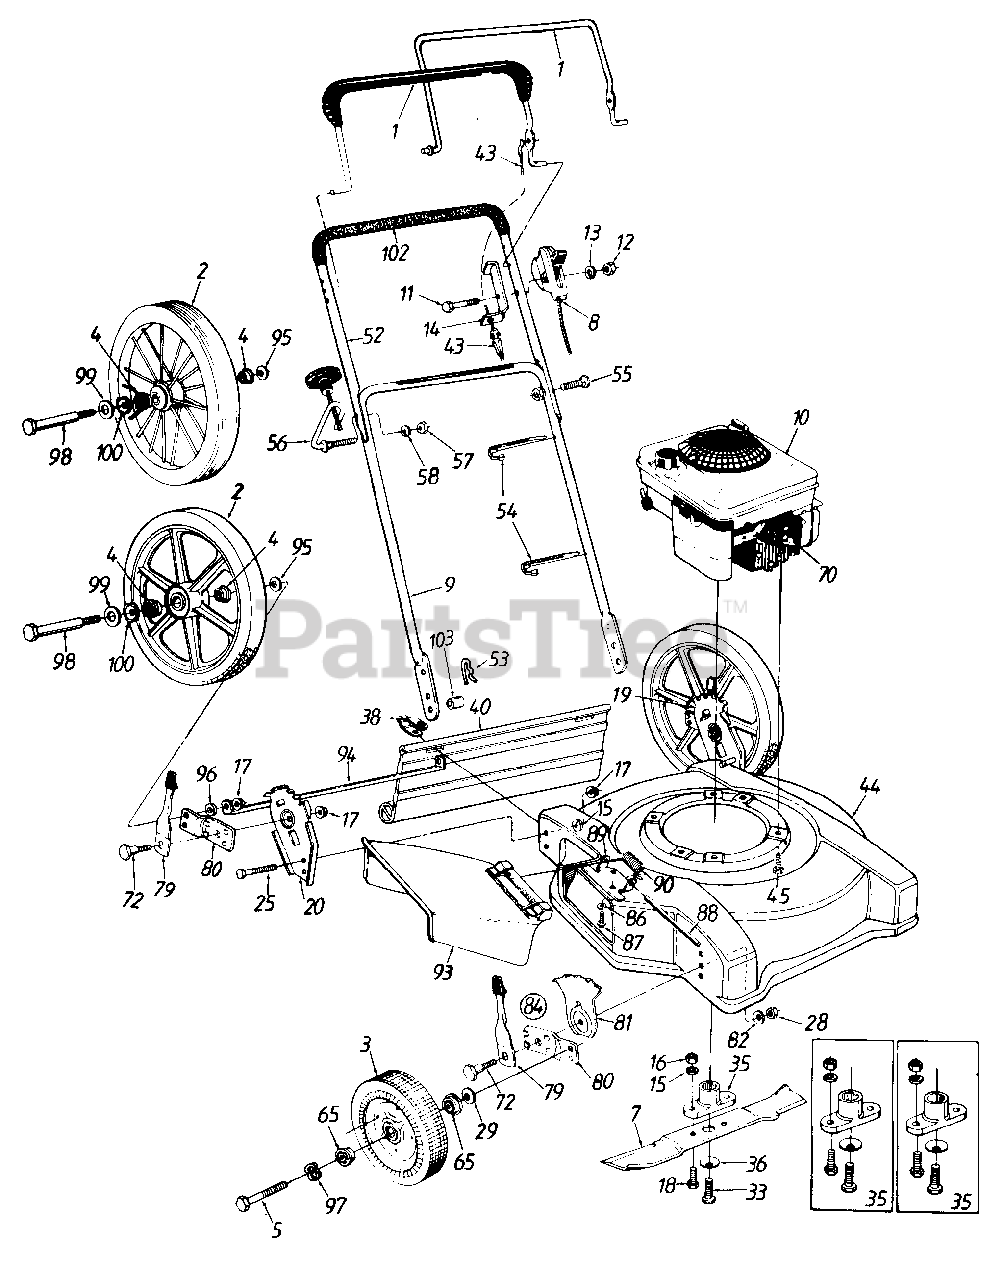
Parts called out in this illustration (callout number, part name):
1	Control Handle
2	16" Wheel Ass'y.-Comp. (Plastic)
3	Front Wheel Ass'y.-Comp.
4	Bearing 1/2" I.D.
5	Front Axle Bolt
7	22" Blade
8	Throttle Control Ass'y. Comp. 51.6"
9	Lower Handle
10	Engine
11	Hex Bolt 1/4-20 x 1.75" Lg.
12	Hex Nut 1/4-20 Thd.
13	Spr. Wash. .265" I.D. x .562"
14	Cable Mtg. Bracket
15	L-Wash. 3/8" I.D.
16	Hex Nut 3/8-24 Thd.
17	Hex Nut 3/8-24 Thd.
18	Hex Bolt 3/8-24 x 1.0" Lg.
19	Wheel Brkt. Ass'y.-L.H.
20	Wheel Brkt. Ass'y.-R.H.
25	Rib Neck Bolt 3/8-24 x .62" Lg.
28	Hex Nut 3/8-16 Thd.
29	Bell-Wash. .400" I.D. x .88"
33	Hex Bolt 3/8-24 x 1.5" Lg.
35	Blade Adapter Kit (Keyed)
36	Bell-Wash. .39" I.D.
38	Hinge Clip
40	Rear Flap Ass'y.
43	Control Cable-39"
44	22" Deck Ass'y.
45	Hex Wash. Hd. TT-Tap Scr. 3/8-16 x 1.00" Lg.
52	Upper Handle
53	Intern. Cot. Pin 5/16" Dia.
54	Cable Tie
55	Curved Carriage Bolt 5/16-18 x 1.38" Lg.
56	Rope Guide Bolt
57	Hex Nut 5/16-18 Thd.
58	L-Wash. 5/16" I.D.
65	Ball Bearing 1/2" I.D.
70	Spark Plug Boot
72	Shoulder Bolt .50" Dia.
79	Spring Lever Ass'y. w/Knob
81	Height Adj. Plate
82	Bell-Wash. .39" I.D. x 1.38"
84	Front Height Adj. Ass'y. Comp.-R.H.
86	Bell-Wash. .285" I.D. x .75" O.D.
87	Hex Wash. Hd. Tap Scr. 1/4-20 x .5" Lg.
88	Hinge Pin
89	Adapter Plate
90	Torsion Spring
93	Chute Deflector Ass'y. Comp.
94	Stabilizer Tube
95	Bell-Wash. .39" I.D. x 1.13
96	Spacer .503" I.D. x .75"
97	Wave Washer .53" I.D.
98	Rear Axle Bolt
99	Fl-Wash. .51" I.D. x 1.0"
100	Spr. Wash. .5" I.D. x 1.0"
102	Foam Grip
103	Spacer
